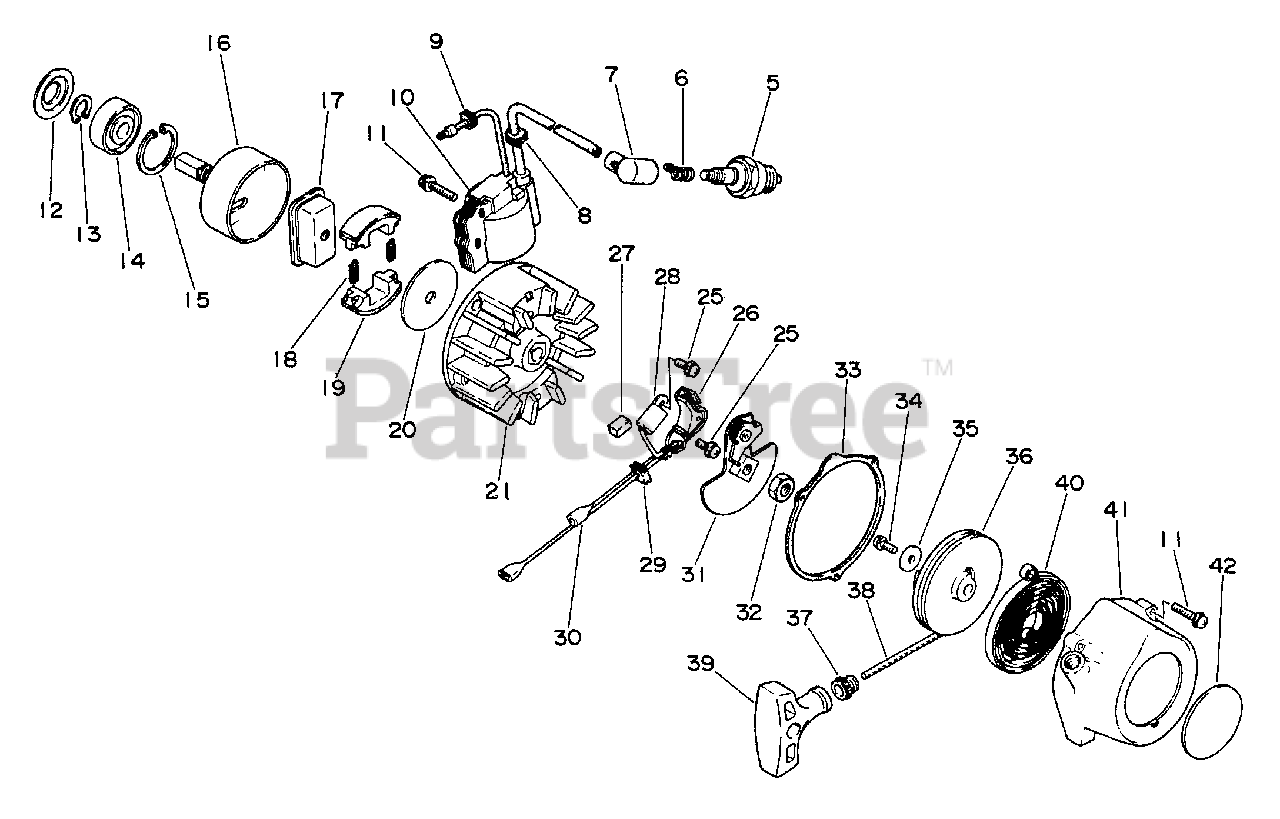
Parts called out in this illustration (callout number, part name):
5	SPARK PLUG -- CJ-8
6	TERMINAL, SPARK PLUG CAP
7	CAP, SPARK PLUG
10	COIL, IGNITION
11	SCREW - 4X20
12	RETAINER, PIPE
13	RING, RETAINING - 12
14	BEARING, BALL - 6201
15	RING, RETAINING - 32
16	DRUM, CLUTCH
17	HUB, CLUTCH
18	SPRING, CLUTCH
19	SHOE, CLUTCH
20	PLATE, CLUTCH
21	FLYWHEEL
25	SCREW - 4X10
26	CONTACT POINT SET
27	PAD, OIL
28	CONDENSER
30	LEAD - GROUND
31	STARTER PAWL ASSY
33	GASKET, STARTER
34	SCREW - 4X10
36	REEL, ROPE
37	ROPE, STARTER - 3X850
38	GUIDE, ROPE
39	GRIP, STARTER
40	SPRING, REWIND
41	CASE, STARTER
42	LABEL - ECHO
